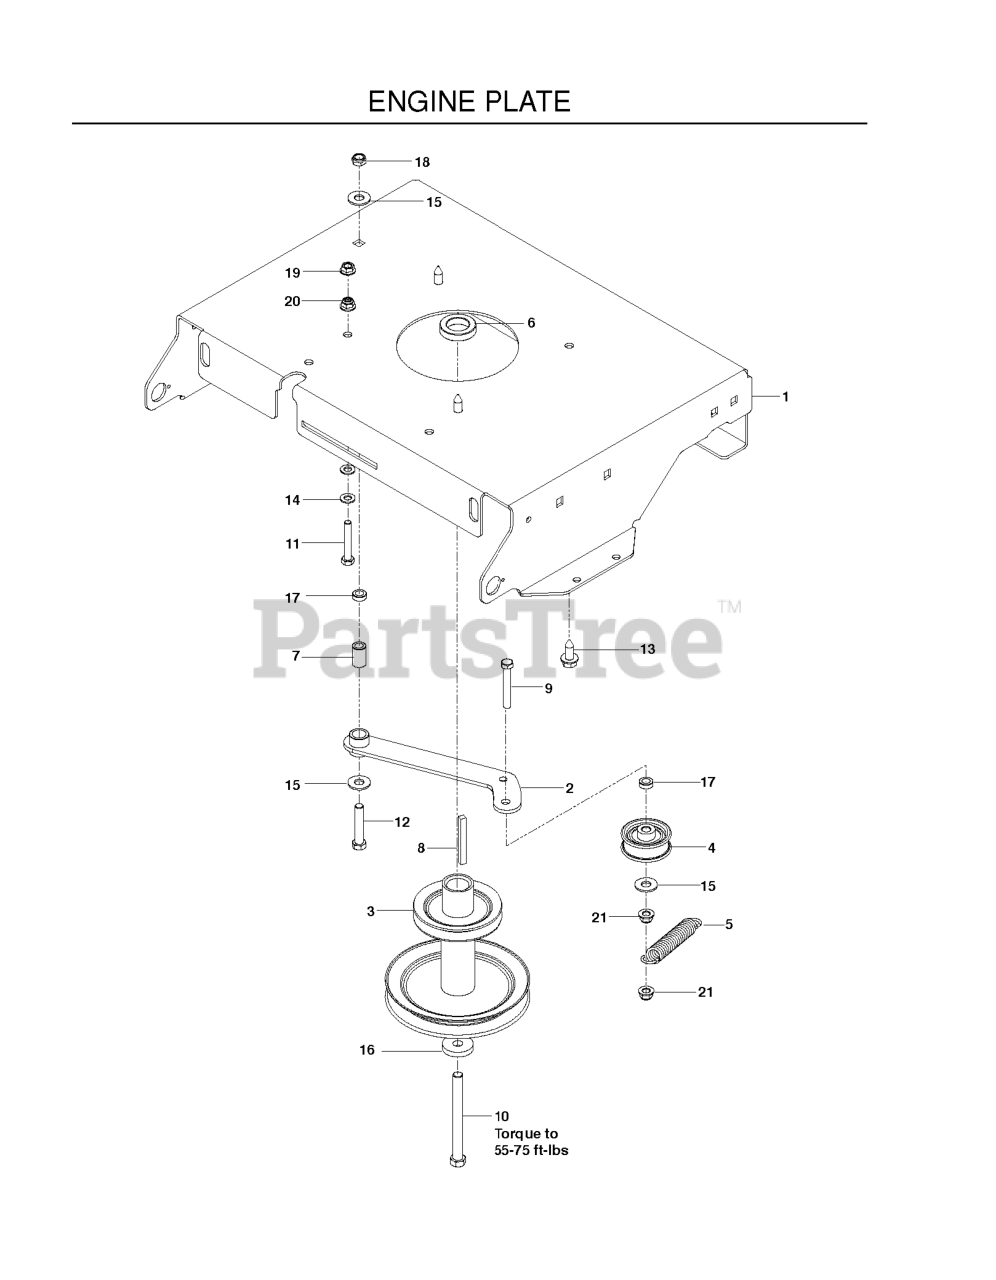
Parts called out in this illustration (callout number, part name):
1	PLATE, ENGINE, ORG
2	!DLER ARM WLDMNT, BLACK
3	PULLEY IDLER
4	PULLEY, ENGINE 6.5
5	SPRING - 3.50
8	KEY 1/4 SQ X 2-1/2
9	HCS 5/16-18 X 2 1/2 TPBLT
10	HCS 7/16-20 X 4 GR5 ZD
11	HCS 5/16-18X2
12	HCS 3/8C X 2
13	HHFS 3/8-16 X 1.0 THD FORMING
14	FLAT WASHER 5/16 SAE
15	WASHER 3/8 FLAT
16	WASHER .43X1.38X.25
17	WASHER 3/8 X 3/4 X .187 TK
18	NUT HEX 3/8-16 NYLON, THIN
19	NUT 5/16C WHIZ
20	5/16-18 NYLOC FLANGE NUT
21	NUT 3/8-16 HEX FLG NYLOC ZD
